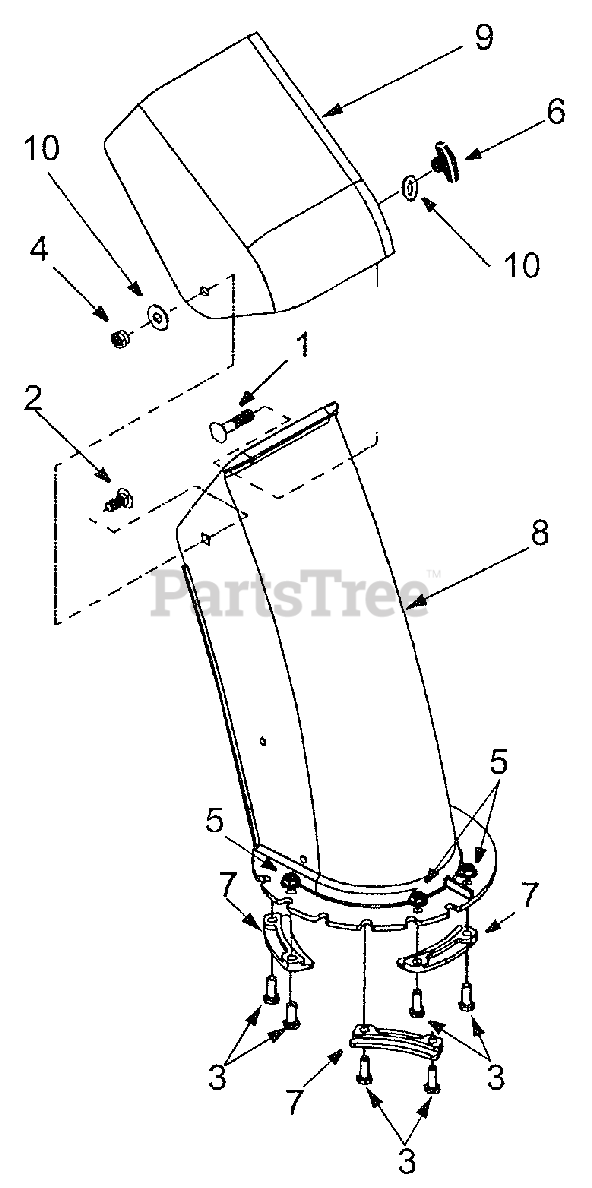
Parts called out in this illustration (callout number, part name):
1	Carriage Screw 5/16-18 x 1.0"
2	Carriage Bolt 5/16-18 x 0.75"
3	Hex Screw 1/4-20 x 0.75"
4	Hex Lock Nut
5	Flanged Lock Nut
6	Knob
7	Chute Flange Keeper
8	Lower Chute
9	Upper Chute
10	Washer
